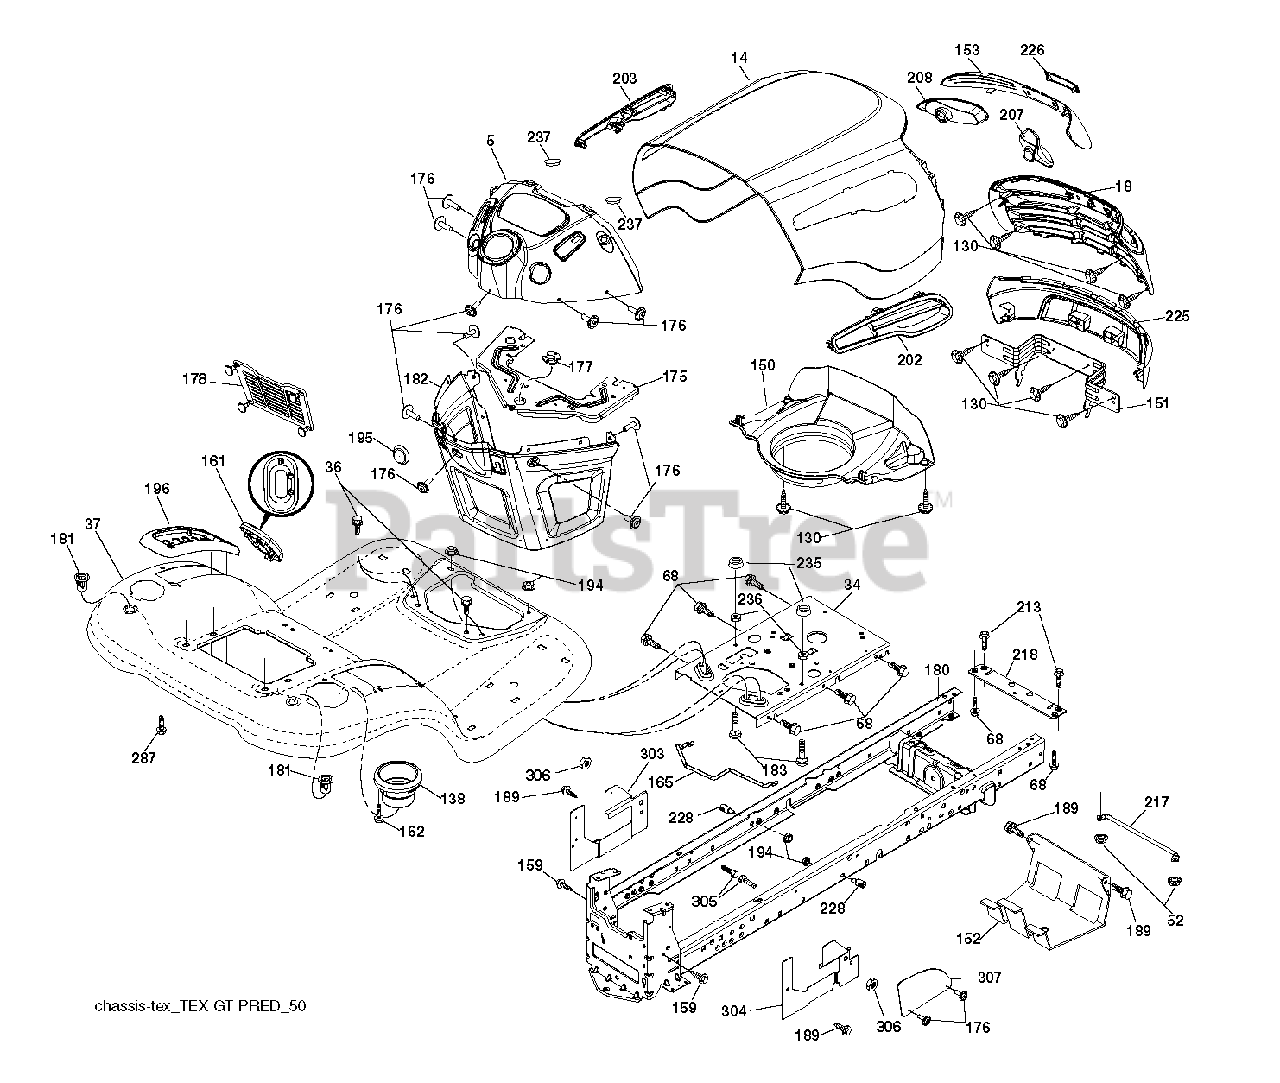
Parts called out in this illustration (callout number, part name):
34	PLATE.ENGINE.WELDED.CHASSIS
36	SCREW 5/16"
52	LOCKNUT
130	SCREW.#10 X 0.750.BOS THREAD
138	CUPHOLDER.TL.TEX.BLACK
152	SHIELD BROWNING
159	SCREW, 3/8-16X3/4
161	WINDOW.FUEL.LT.TEX.BLACK
162	SCREW.HI-LO.CONSOLE
165	SUPPORT.TANK.REAR.W/TE
175	PLATE.CROSSMEMBER.HUSQ
176	SCREW.#10-24X5/8.RN.QU
177	BUSHING,STEERING
178	CARGO.ASM.NET.TXGT.W/C
180	CHASSIS
181	FEND/FTRST.PCH.CPH.NFW
182	DASH.LOWER.COMMON.12V.ADAPTOR
183	BOLT.5/16-18X1-1/4 FULL THD
189	SCREW
194	NUT LOCK HEX FLANGE 5/16-18
195	PLUG.HOLE.DASH.LOWER.12V.BLK
196	CONSOLE.ASM.DECKLFT.BL/RBT.TLT
213	BOLT
217	ROD.PIVOT.HOOD
218	X-PIECE.HOOD.STOP.NON/
228	STUD.FASTNER.W/ANTI-ROTATE
235	SPACER FENDER
236	NUT.CENTERLOCK.5/16-
237	PLUG.MOUNT.CARGO.BLK
306	NUT LOCK FLG 3/8-16 UNC
